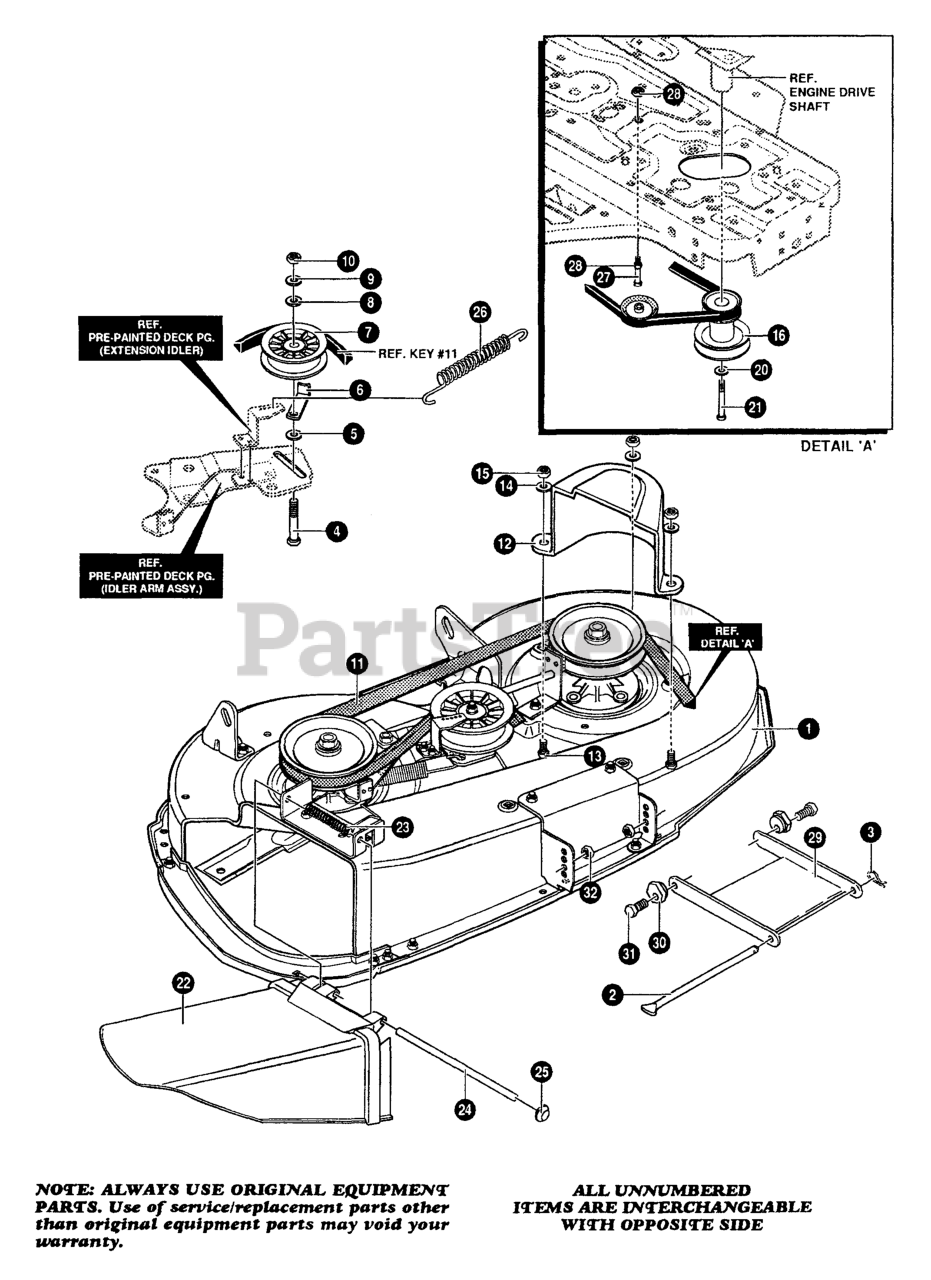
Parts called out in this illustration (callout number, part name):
1	ASSEMBLY, 40" DECK
2	ROD, DECK HITCH
3	PIN, HAIR
4	BOLT, 3/8-16 X 2.00
5	WASHER, FLAT .386 X 1.25 X .09
6	RETAINER, BELT
7	PULLEY, IDLER
8	WASHER, FLAT .391 X 1.00 x .209
9	WASHER, .393 X .68 X .10
10	NUT, 3/8-16
11	BELT, V 5L 81.00
12	GUARD, BELT LH
13	SCREW, 5/16-18 x 0.75
14	WASHER, FLAT .344 x .69 X .065
15	NUT, 5/16-18 R
16	PULLEY, ENGINE
20	WASHER, .459 X .78 X.1 2
21	SCREW, 7/16-20 x 4.25
22	CHUTE DEFLECTOR
23	SPRING, TORSION CHUTE DEFLECTOR
24	ROD, PIVOT DECK
25	NUT, PUSH ON CAP
26	SPRING, TENSION
27	SCREW, 3/8-16 x 7.50
28	NUT, 3/8-16
29	BRACKET, LINK DECK FRONT
30	NUT, ADJUST
31	SCREW, 5/16-18 x 1.00
32	NUT, 5/16-18
